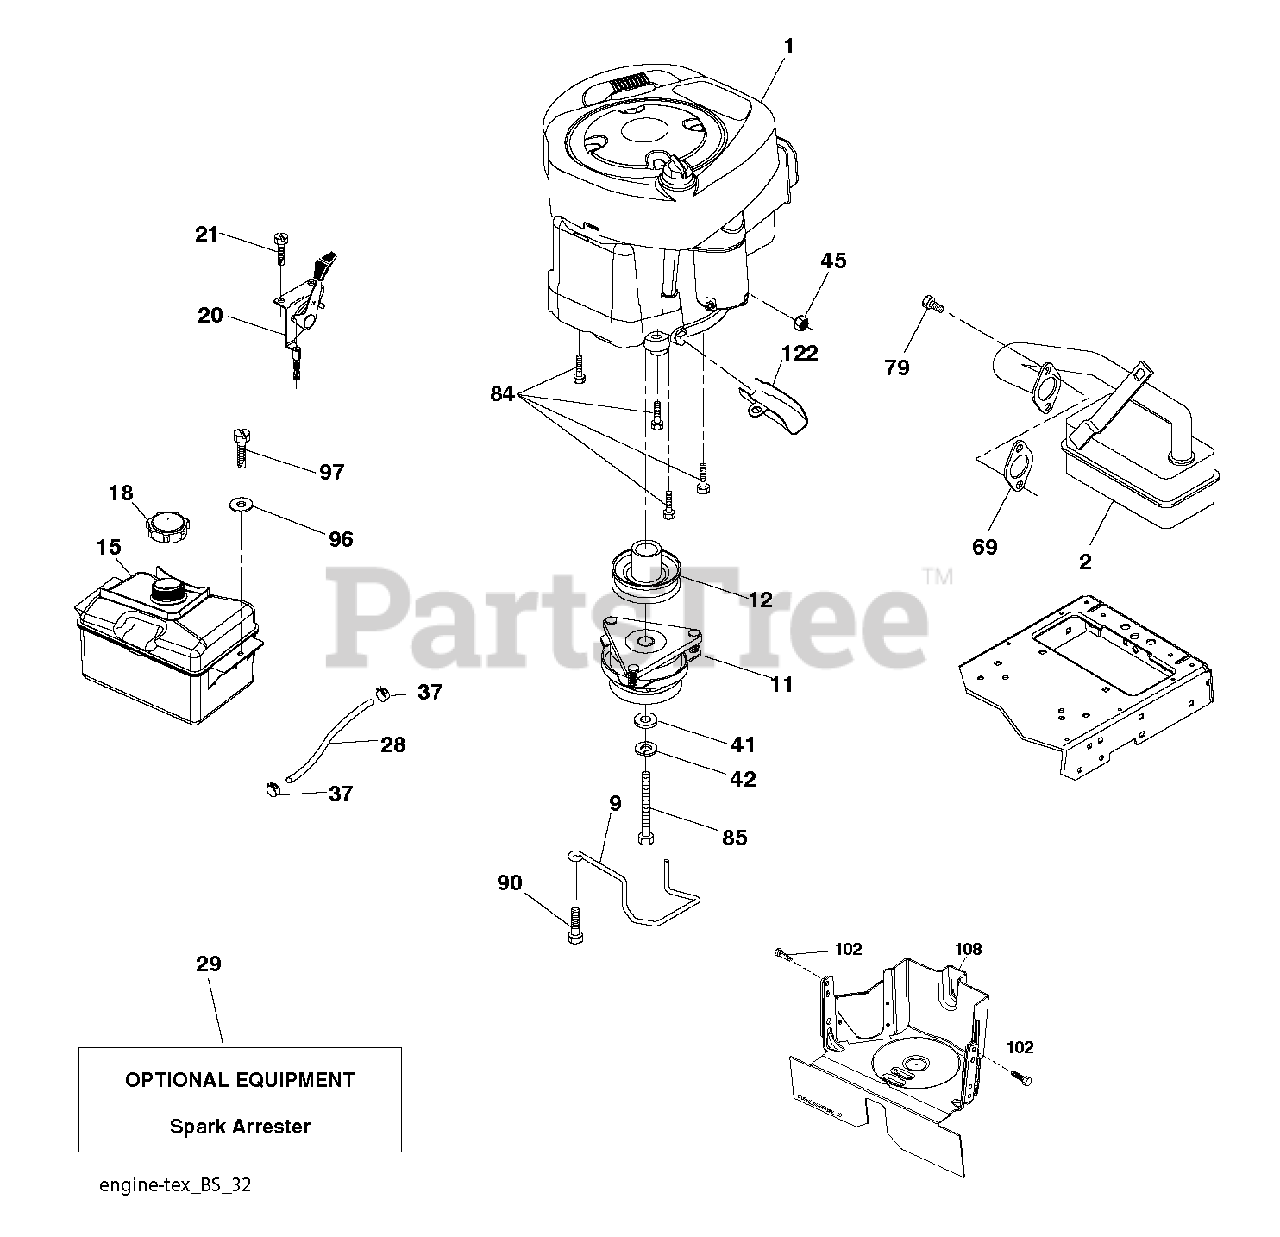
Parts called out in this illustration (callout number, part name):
2	MUFFLER.LT.BRIGGS.14HP.IC/OHV
9	KEEPER BELT ENGINE
11	CLUTCH.ELECTRIC.LT.48"*
12	PULLEY.ENGINE.TUFFTORQ
15	FUEL.TANK.ASM.NON-EPA
18	CAP ASM.FUEL.2.25"FR.
20	CONTROL.TH/CK.C.
21	SCREW.#10 X 0.750.BOS
28	LINE.FUEL.20
29	KIT.SPARK ARRESTOR 794945 B&S
37	HOSE CLAMP
42	LOCKWASHER
45	NUT
69	REPL BY 532 27 22-93
79	SCREW.SOCKET HD.5/16-1
84	SCREW.3/8-16
85	BOLT HEX 7/16-20X4-1/4"
90	SCREW 3/8-16X1
97	SCREW HEXWSHR 1/4-20X3/4
102	SCREW 5/16-18X1
108	COVER PULLEY
122	EXTENSION DRAIN OIL
